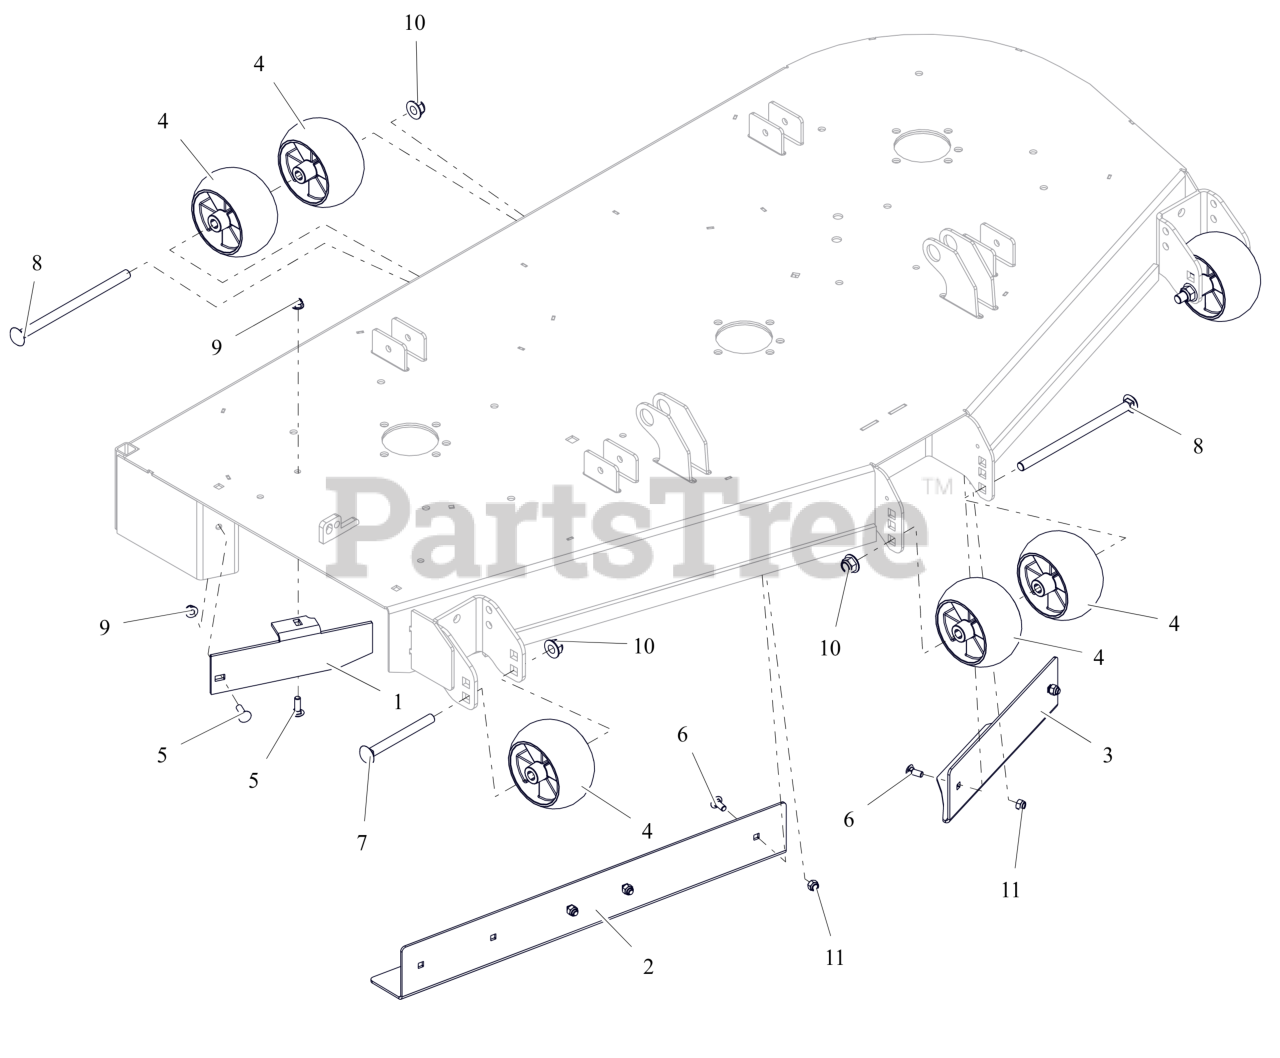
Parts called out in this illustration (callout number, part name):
1	BAFFLE, 60" DISCHARGE
2	BAFFLE, 60" RH VACUUM (ORANGE)
3	BAFFLE, 60" LH VACUUM (ORANGE)
4	WHEEL, ANTI SCALP - 5X3 CTR W/RIBS
5	BLT,RHSN .31-18X1.00 G5 ZCC
6	BLT,RHSN .31-18X.75 G5 ZCC
7	BLT, RHSN .50-13X5.00 G5 ZCC
8	BTL,RHSN .500-13 X 8.5S G5 ZCC
9	NUT,LK-NYL-FLG .31-18 G5ZC120
10	NUT,NYL-FLG .50-13 GF ZCC
11	NUT,NYL .31-18 G5 ZCC
